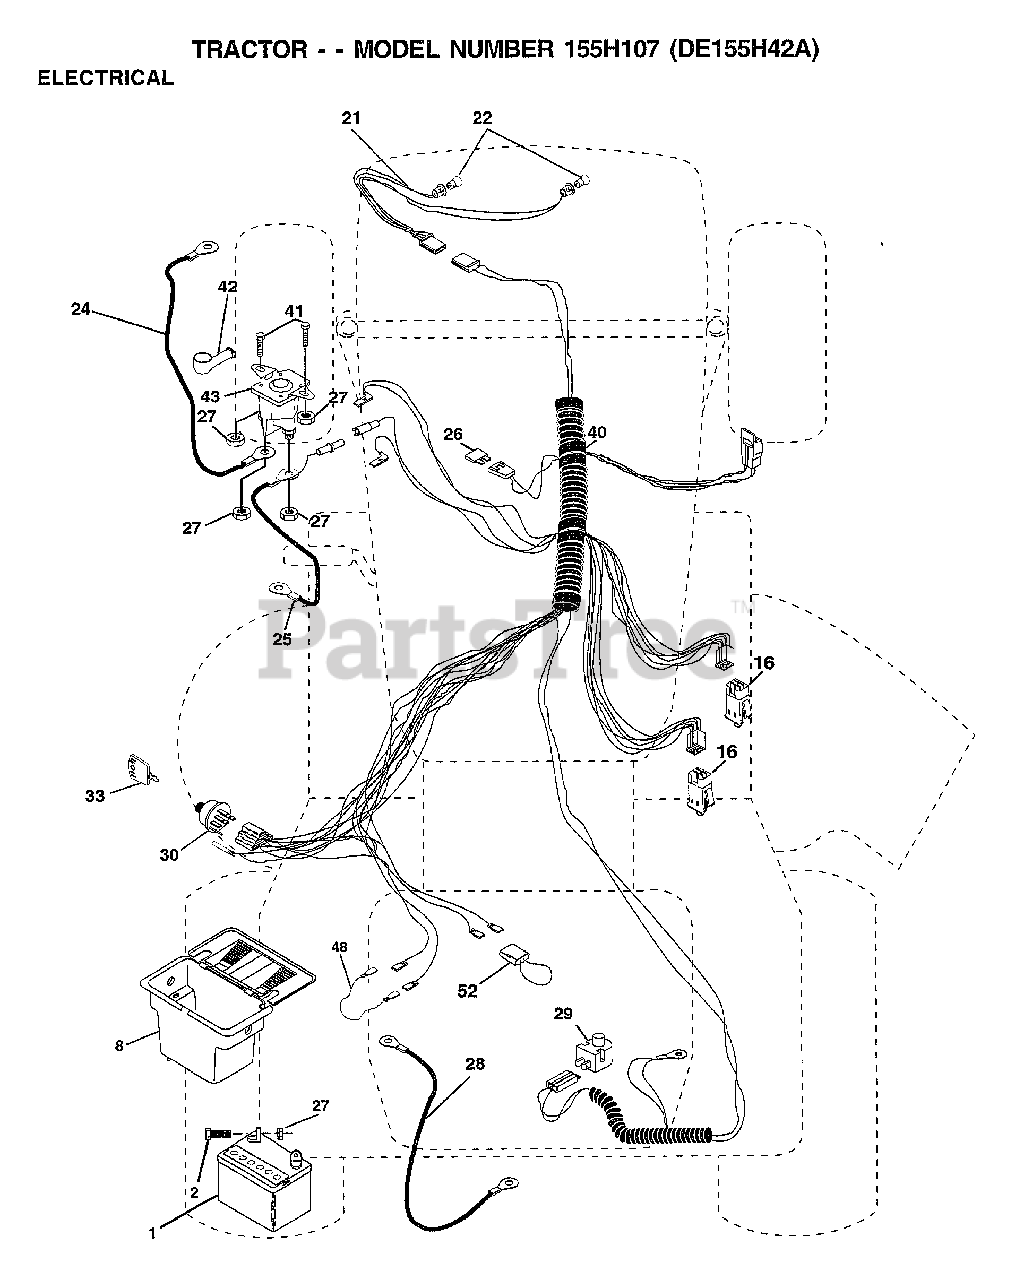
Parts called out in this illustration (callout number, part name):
2	BOLT LT
8	"CASE,BATTERY.MECH"
16	SWITCH INTERLOCK
21	HARNESS.ASM.LIGHT W/4152J
22	HEADLAMP BULB
24	"CABLE T, BATTERY"
25	CABLE.BTRY.6GA.RD
26	FUSE.15 AMP
27	NUT
28	CABLE T
29	SWITCH SEAT
30	SWITCH.IGN.
33	KEY MLD GEN DELTA
40	HARNESS IGN
41	BOLT HXHD FIN
48	ADAPTER AMMETER
52	PROTECTION LOOP
